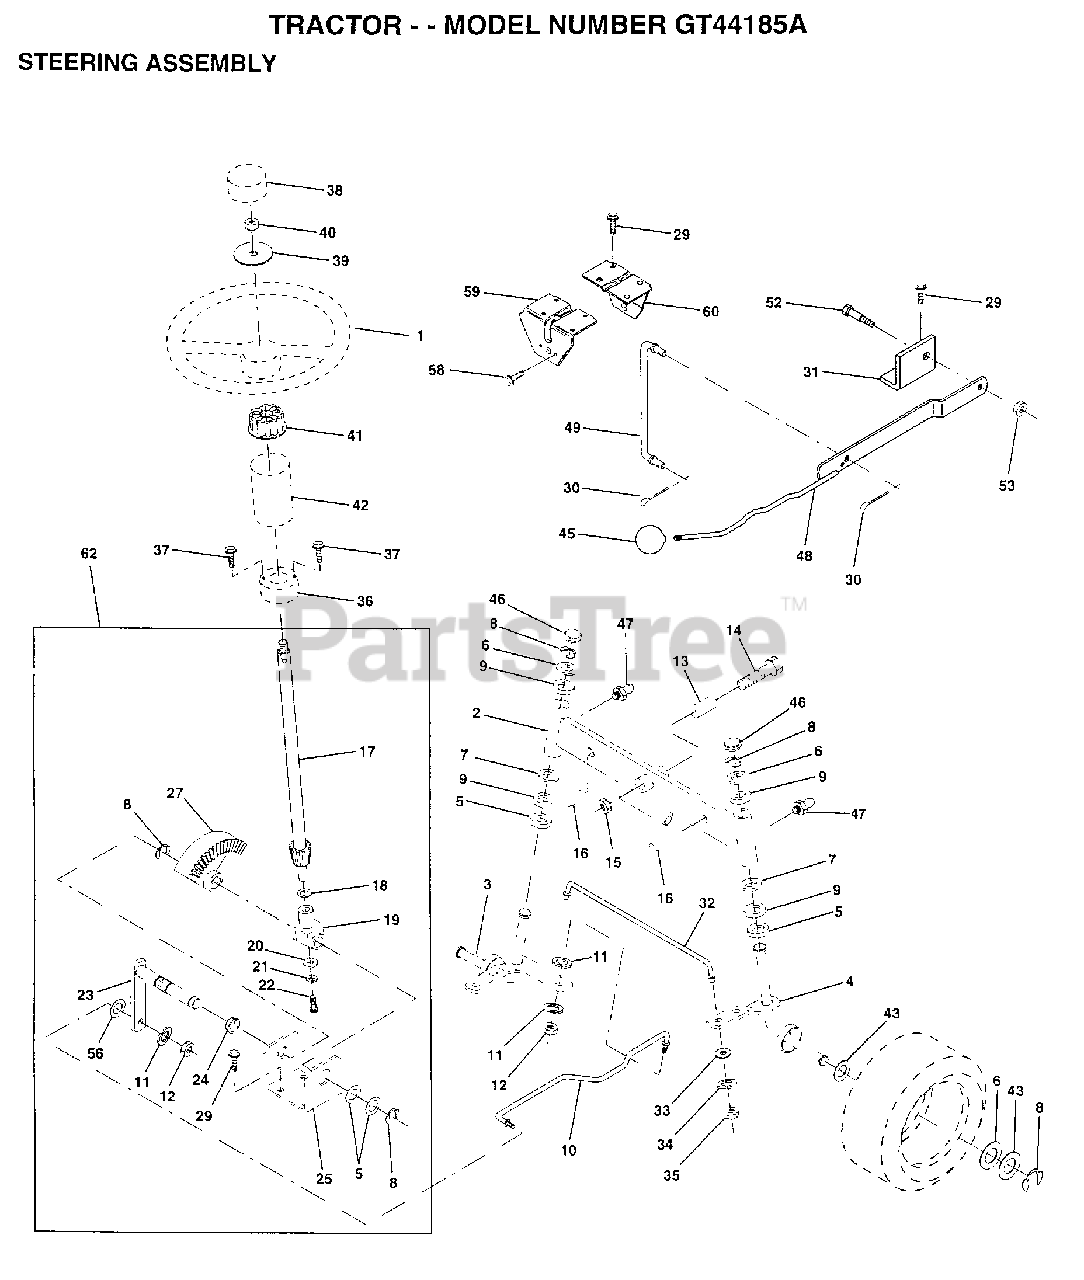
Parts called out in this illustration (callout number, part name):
1	WHEEL STR AYP BLK
2	AXLE ASM FRONT
5	WASHER .T
6	WASHER
7	WASHER
8	RING
9	COL. SRTG. BEAR.
11	LOCKWASHER
13	BEARING
14	BOLT LT
15	"NUT-LOC,FLANGE LT"
16	AXLE PIN
17	STEERING SHAFT
18	THRUST WASHER
19	SUPPORT.SHAFT
21	LOCKWASHER
22	SCREW.SCKTHD.CAP
24	NYLINER T
25	"BRKT,STEERING"
27	GEAR SECTOR
29	SCREW
30	COTTER PIN
31	BRKT.PVT.MAN.LVR.
32	ROD.TIE.19.75
33	WASHER M
34	LOCKWASHER
35	NUT.LOCK.5/16-24
36	BUSHING.STRG.3/4
37	"SCREW-TT,10-32 FL"
38	CAP STEER AYP
39	WASHER
41	ADAPTER LT
42	BOOT SHAFT STEER
43	WASHER
45	KNOB T (1/2-HOLE)
46	CAP
47	ZERK M
48	LEVER.CLUTCH.MOWR
49	LINK CLTCH W/NUTS
52	"BOLT, SHOULDER LT"
56	WASHER
58	SCREW LT
59	SUPPORT-SADDL T
60	SUPPORT.SADDLE.FT
